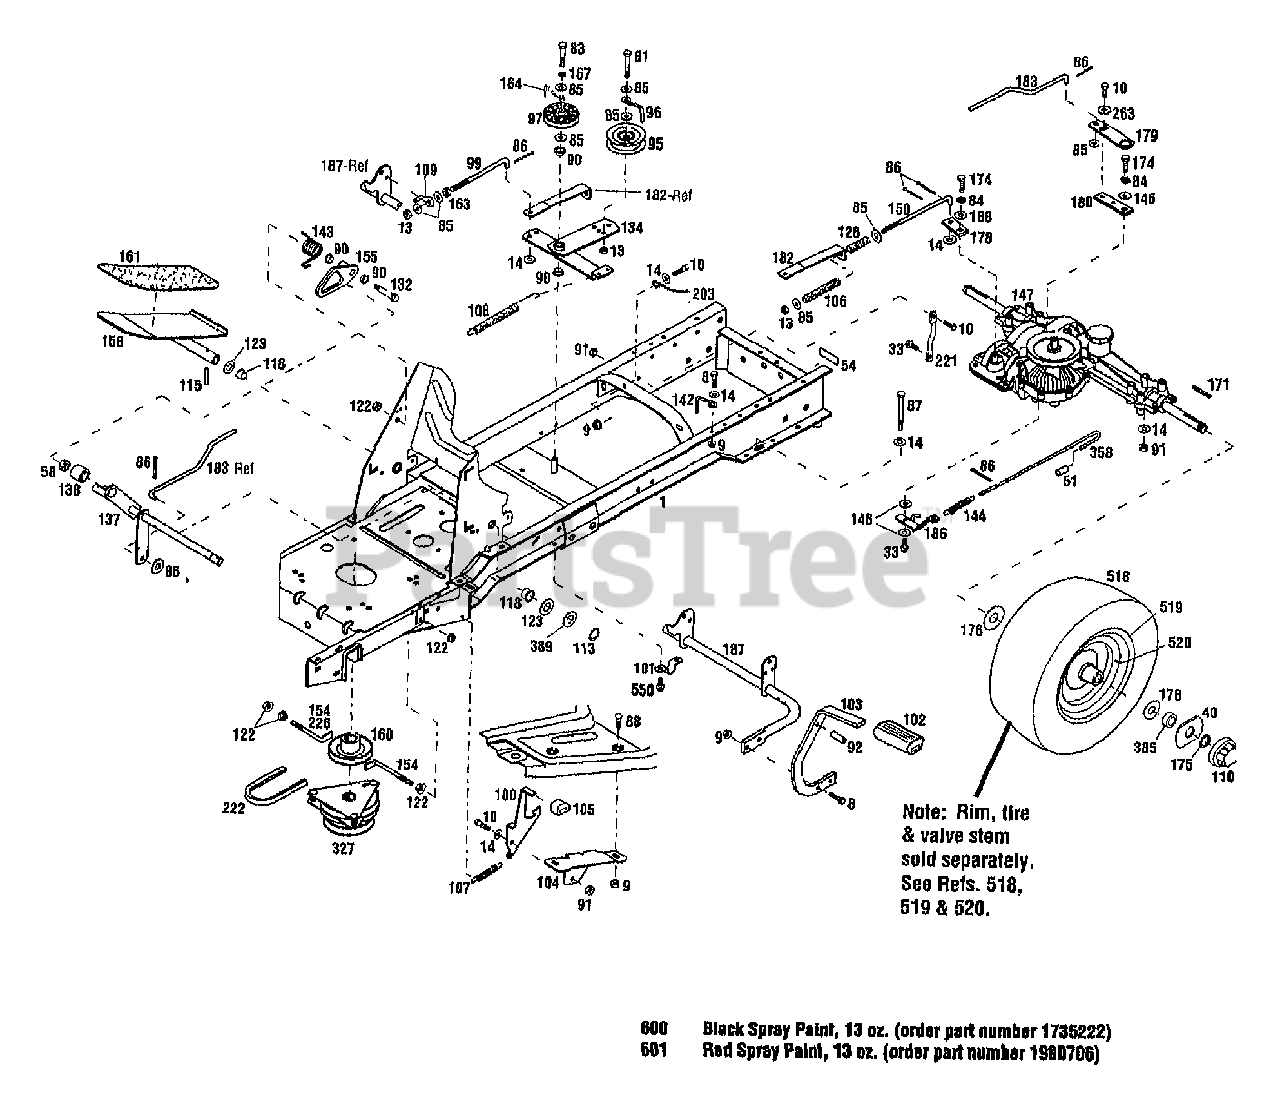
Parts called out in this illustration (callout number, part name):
1	ASSM-FRAME LTX
8	SCR-HH 5/16-18X1.0 G5 ZP
9	NUT-HFLK 5/16-18 ZP
10	SCR-HHC 5/16-18X.75 GR 5 ZP
13	NUT-LOCK 3/8-16
14	WASHER-FLAT 5/16 SAE
33	SCR-HFLK 5/16-18X.75
40	WASHER-SPEC .75X2.50
51	GRIP-HANDLE
54	DECAL-TRANS RELEASE
58	NUT-HT LK 1/4-20
81	SCR-HH 3/8-16X2.0 G5 ZP
83	SCR-HH 3/8-16X1.75 G5 ZP
84	WASHER-LK .25 ZP
85	WASHER-FLAT 3/8 SAE
86	PIN-COTTER .09X.75 ZP
87	SCR-HH 5/16-18X2.75 G5 ZP
88	SCR-CARR 5/16-18X.62 G2 ZP
90	BUSHING-.5X.5 NYLON FLNG
91	NUT-TOP/LK 5/16-18 ZP
92	PIN-.312X.75
96	GUIDE-BELT
97	PULLEY-IDLER
99	ROD-CLUTCH
100	LATCH-BRAKE CLUTCH USE1771514
101	CLIP-CLAMP .75 ID
102	PAD-FOOT PEDAL
103	PEDAL-BRAKE
104	BRKT-BRAKE LOCK
105	PAD-BRAKE
106	SPRING-COMPRESSION
107	SPRING-EXTENSION
108	SPRING-EXTENSION
109	ROD-PIVOT
110	CAP-HUB
113	RING-RETAIN .625 ID
115	PIN-ROLL .188X1.0
118	BEARING-FLANGE
122	NUT-HFLK 3/8-16 ZP
123	WASHER-1.115X.637X.06
132	SCR-SHLDR 3/8-16
134	ARM-IDLER
137	SHAFT-HYDRO PIVOT
138	BEARING-BALL
142	GUIDE-BELT
143	SPRING-TORSION
144	SPRING
146	WASHER-FLAT 5/16 SAE
147	TRANSAXLE-HYDRO
150	ROD-BRAKE
154	RETAINER-CLUTCH {13035/036}
154	RETAINER-CLUTCH {13037}
158	ASSM-PEDAL HYDRO
160	PULLEY-ENGINE
161	PAD-FOOT PEDAL
163	NUT-HEX 3/8-16 ZP
164	GUIDE-BELT
167	WASHER-LK .375 @ DEPL
171	KEY-3/16X3/16X1 3/4
174	SCR-HHC 1.4-28 X .50
175	RING-RET."E".577 ID
176	WASHER-1.87X.765X.06 SPECIAL
178	BRAKE-ARM
179	ARM-CONTROL
180	ARM-HYDRO
182	BRACKET-BRAKE
183	ROD-HYDRO CTRL
186	BRACKET-DUMP VALVE
187	ASSM-BRAKE PEDAL
188	WASHER-FLAT .25 DIA
203	GUIDE-BELT
221	SUPT-TRANSAXLE
222	BELT-V
226	GUIDE-BELT {13035/036}
263	WASHER-LK .312 PYRAMIDAL
327	CLUTCH-ELECTRIC
358	ROD-DUMP VALVE
385	SPACER-1.0X.766X.413
389	WASHER-1.0X.64X.029
518	TIRE-20X8.00-10
519	WHEEL-REAR
520	STEM-VALVE
550	SCR-HFLK 5/16-18X.75
600	PAINT-BLACK SPRAY
601	PAINT-RED SPRAYCAN POWDER
